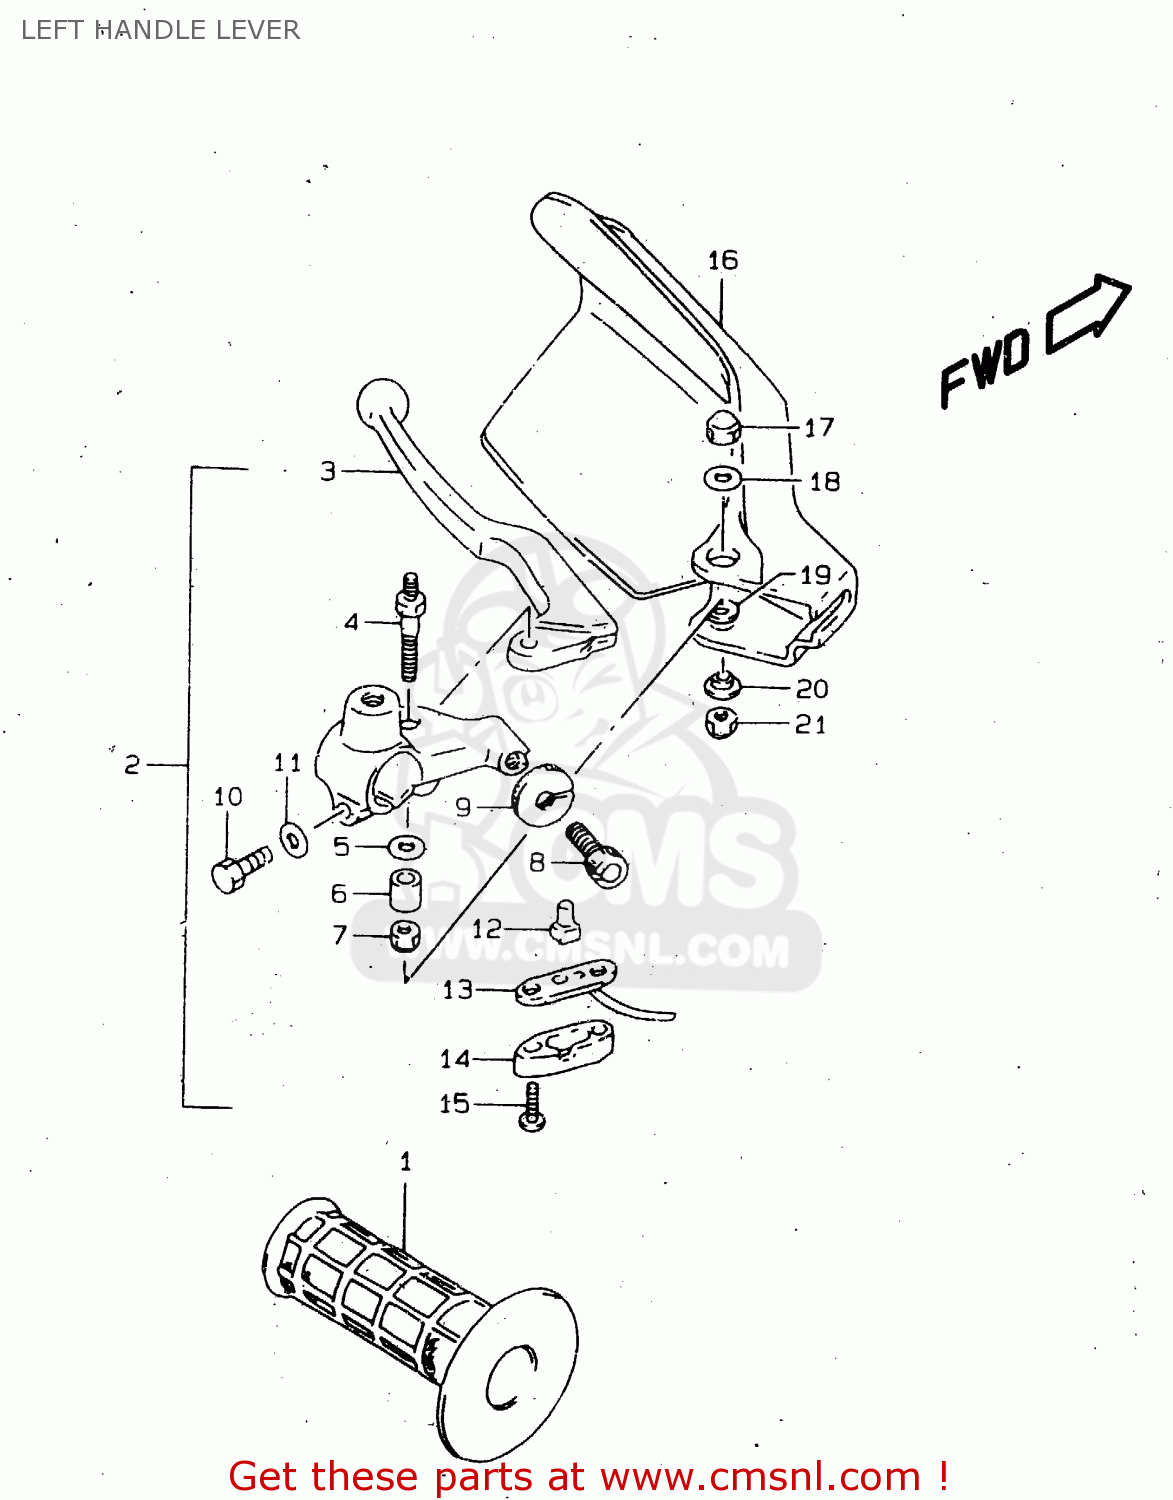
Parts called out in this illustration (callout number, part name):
1	GRIP,L
2	LEVER ASSEMBLY,CLUTCH
3	LEVER,CLUTCH
4	BOLT,CLUTCH LEVER PIVOT
5	WASHER
6	SPACER,LEVER SET
7	NUT
8	ADJUSTER,CABLE
9	NUT,CABLE ADJUSTER LOCK
10	BOLT
11	WASHER
12	CONTACT,SWITCH
13	HARNESS ASSY,WIRE
14	COVER,FR BK TERMINAL BASE
15	SCREW
16	COVER,KNUCKLE,LEFT
17	NUT
18	WASHER(6.5X20X1.6)
19	WASHER(6.5X16X1.2)
20	WASHER
21	NUT 6MM
